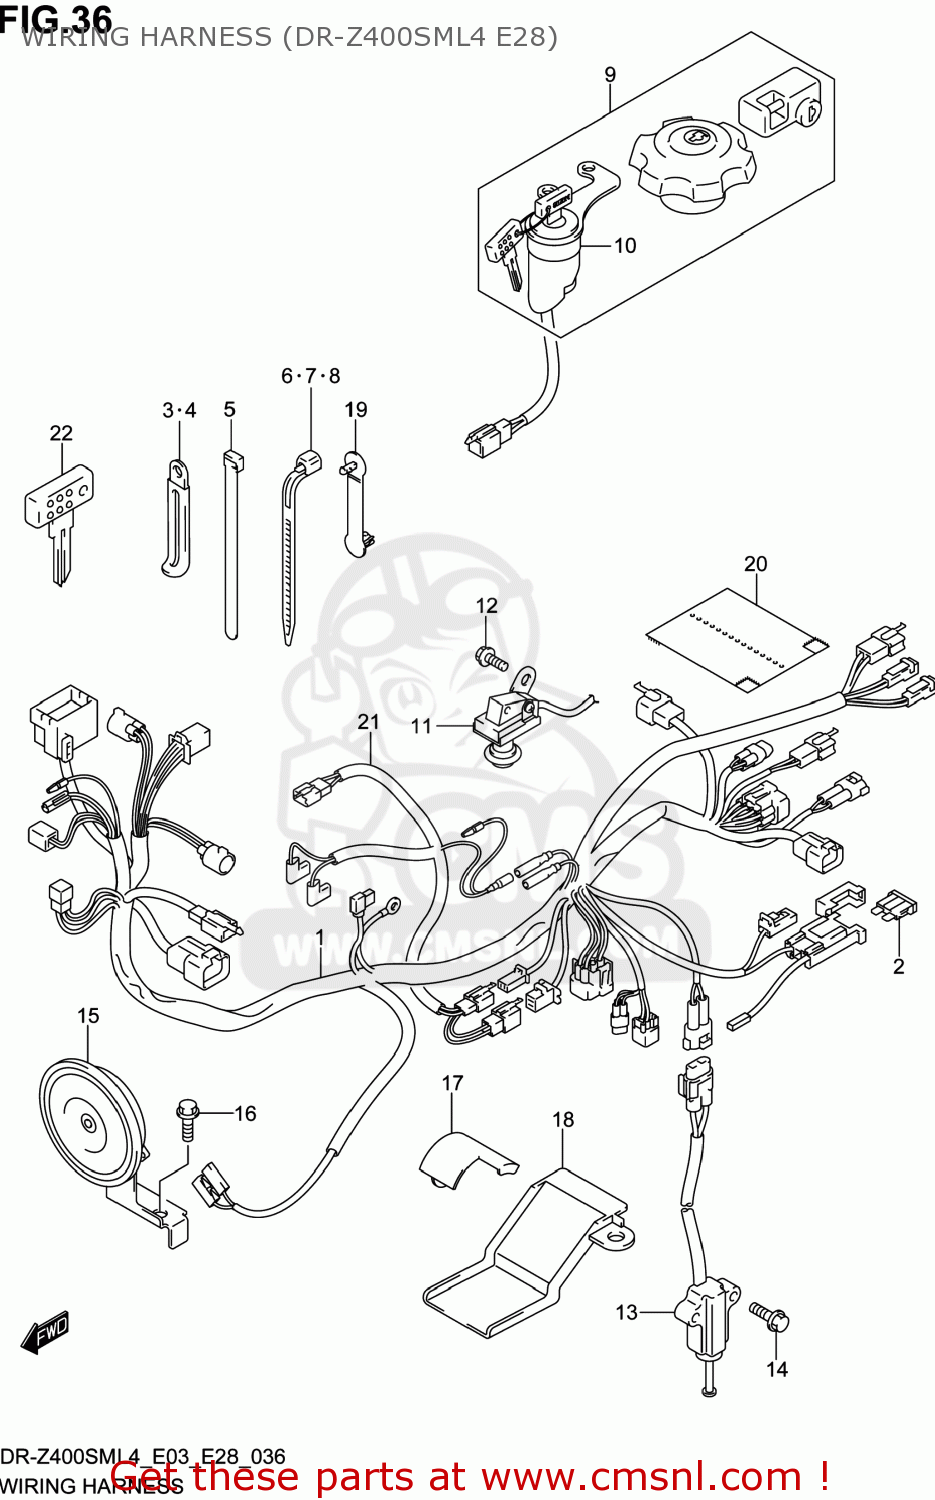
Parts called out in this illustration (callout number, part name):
1	HARNESS,WIRING
2	FUSE(20A)
3	CLAMP(L:45)
4	CLAMP(L:80)
5	CLAMP(L:145)
6	CLAMP(L:125)
7	CLAMP(L:165)
8	CLAMP(L:235)
9	LOCK SET
10	SWITCH ASSY,IGNITION
11	SWITCH ASSY
12	SCREW
13	SWITCH ASSY,SIDE STAND
14	BOLT
15	HORN ASSY
16	BOLT
17	PROTECTOR,WIRING HARNESS
18	PROTECTOR,WIRING HARNESS
19	CLAMP(L:63)
20	COVER,WIRING HARNESS
21	WIRE,CARB HEATER
22	KEY,BLANK(TYPE:C)
